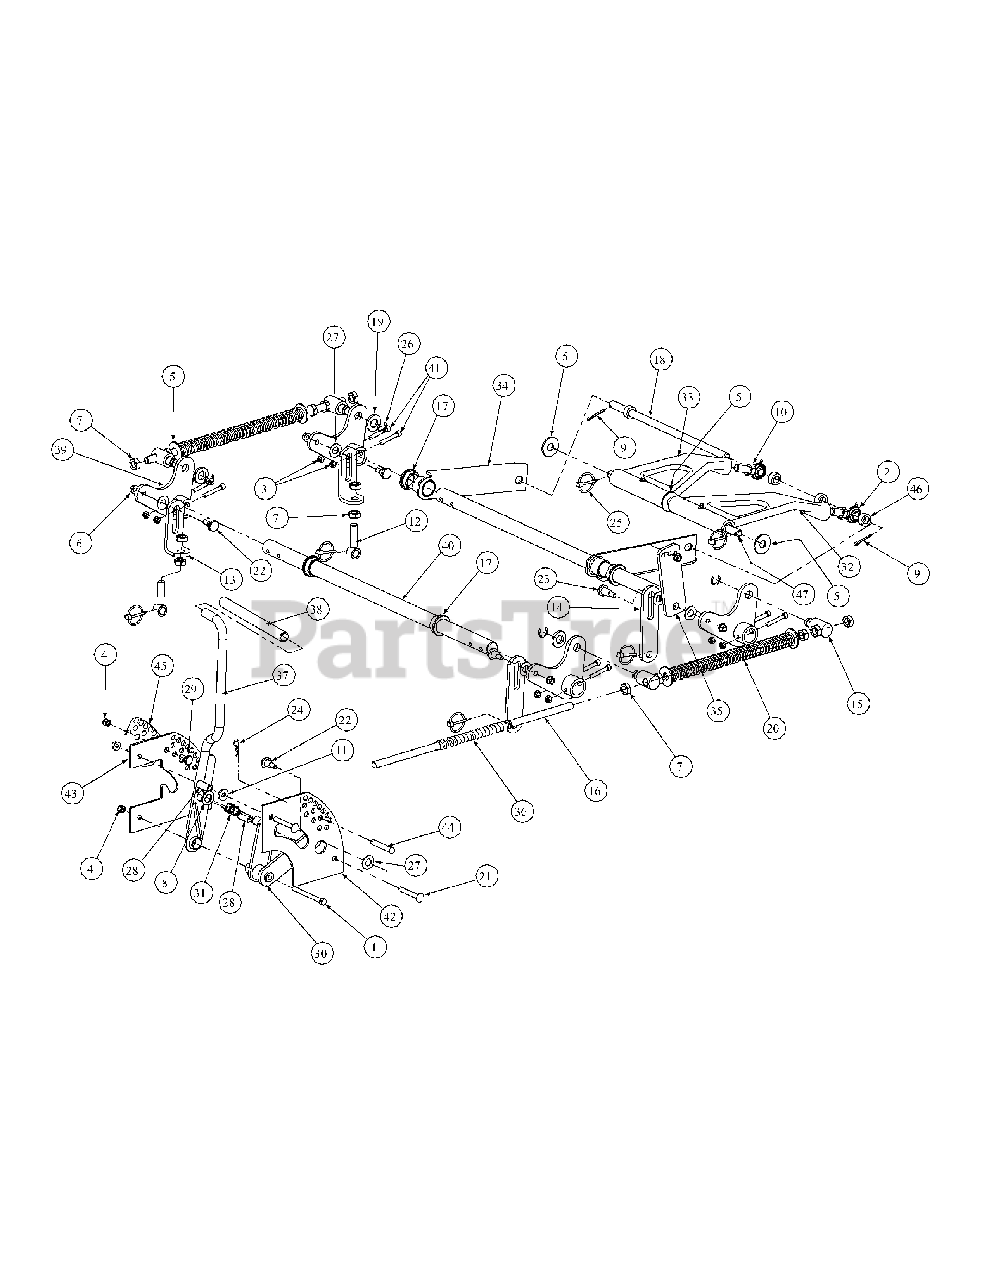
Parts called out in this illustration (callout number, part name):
1	Hex Cap Screw, 3/8-16, 3.75
2	Rod End, Male
3	Nut, 5/16-18, Nylock
4	Nylock Insert Lock Nut, 3/8-16
5	Flat Washer, 5/8
6	Hex Nut, Flange Lock, 3/8-16
7	Jam Nut, 5/8-11
8	Flat Washer, .06, .776, 1.25
9	Cotter Pin, 3/16 x 1-1
10	Jam Nut, 5/8-18
11	Idler Washer
12	Eye Bolt, 5/8ID
13	Eye Bolt Mount Link, 5/8 ID
14	Deck Link
15	Ferule Lift
16	Lift Connector Rod
17	Hex Flange Bearing, 1.25 ID
18	Front Lift Link, Rod Mount
19	Spacer, .812 ID x .268 Lg.
20	Lift Compression Spring
21	Carriage Bolt, 3/8-16, 2.75
22	Shoulder Screw, 0.625 OD x .437 Lg.
23	Shoulder Screw, 0.625 OD x .830 Lg.
24	Cotter Pin, .148 x 3.00
25	Linch Pin, 3/16 Dia.
26	E Clip, 3/4 Dia.
27	Nylon Flat Washer, 5/8
28	Spacer, .39 ID x .63 OD x 1.442
29	Shoulder Screw, .50 OD x 0.27
30	Lift Pivot Assembly
31	Lift Handle Spring
32	Bearing Lift Brace Assembly, Right Hand
33	Bearing Lift Brace Assembly, Left Hand
34	Front Frame Strut Assembly
35	Lift Link Adjustment
36	Hose, 5/8 ID 13/16 OD, 8" LG
37	Lift Handle Assembly
38	Lift Handle Grip
39	Bellecrank Weldment Assembly
40	Deck Lift Shaft
41	Socket Head Cap Screw, 5/16-18 x 2
42	Outer Lift Index Plate
43	Inner Lift Index Plate
44	Clevis Pin, .438 Dia. x 2.625 Lg.
45	Decal Height Indicator
46	Spacer, .630 ID x 1.06 OD x .440
47	Lift Link Rod
